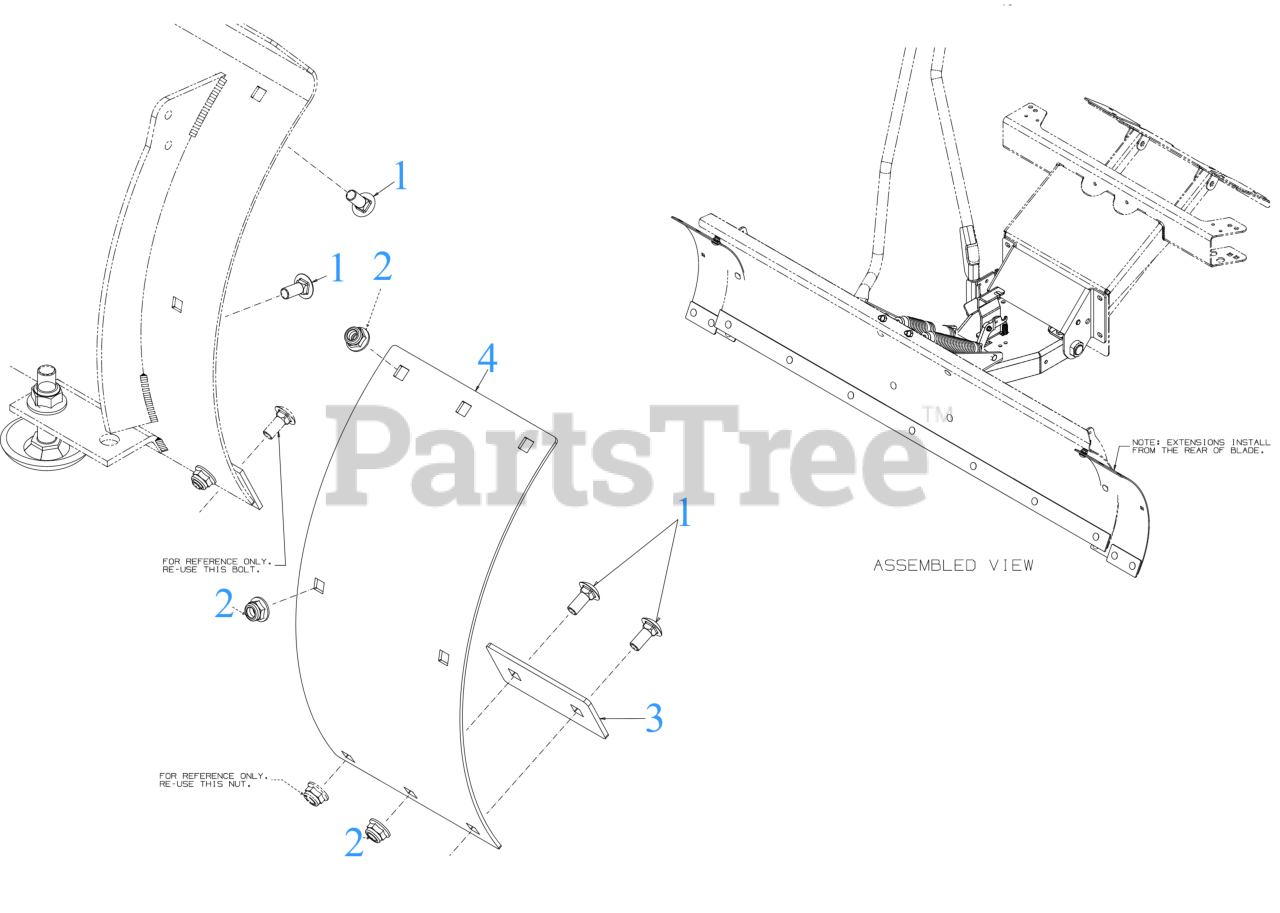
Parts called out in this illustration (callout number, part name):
1	CARRIAGE BOLT 5/16-18 x .75
2	FLANGE LOCK NUT 5/16-18
3	PLATE
4	EXTENSION
